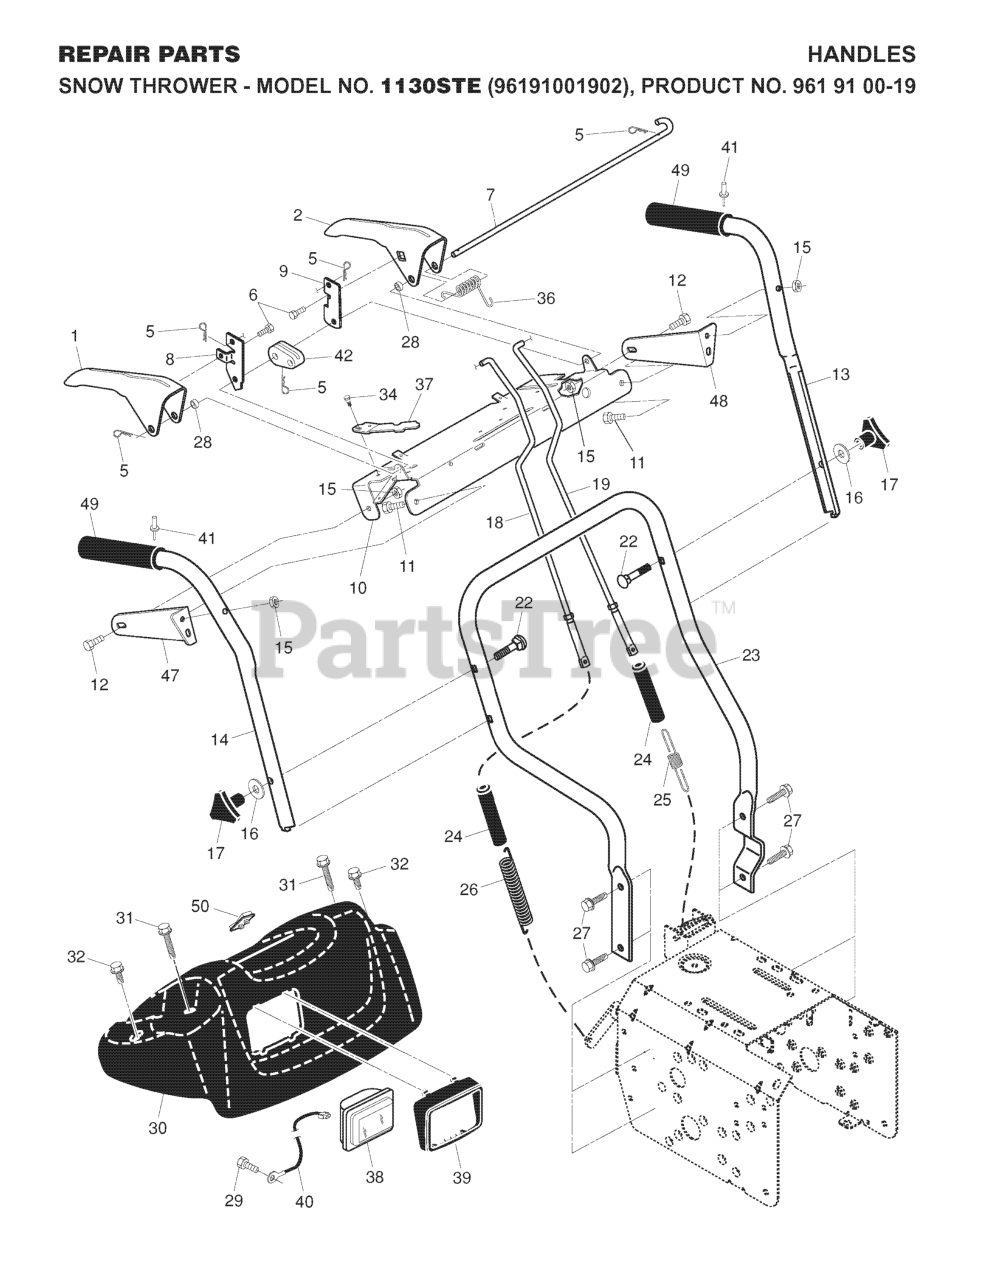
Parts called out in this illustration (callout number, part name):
1	LEVER.CONTROL.RH.PNT
2	LEVER.CONTROL.LH.PNT
5	SPRING RETAINER
7	BAIL.CONTROL.INTERLOCK
8	ARM,IMPELLER ROD
9	ARM.TRACTION.ROD.YZ
10	PANEL.CONTROL.PNT.BLACK
11	HEX BOLT
12	BOLT.FIN.HEX.5/16-18X3/4
13	TUBE.HANDLE.PLOW.LH.PNT
14	TUBE.HANDLE.PLOW.RH.PNT
15	NUT.LOCK.5/16-18
16	WASHER
17	KNOB.HANDLE.3/8.TRI-POINT.BLAC
18	ROD.ASM.IMPELLER
19	ROD.ASM.TRACTION.
22	BOLT 3/8-16 X 2-1/4
23	TUBE.LOWER.HANDLE.24.BLACK
24	SLEEVE, SPRING
25	SPRING, TRACTION DRIVE
26	SPRING, AUGER CONTROL
27	SCREW 3/8-16X1
28	SPACER CONTROL LEVER
29	Screw, Grounding
30	CONSOLE, PANEL
31	SCREW, HEX HD TAPPING #10-24 1
32	SCREW, HEX HEAD, TAPPING
34	SCREW 14-20 X 5/8
36	RP SPRING, TORSION
37	SPRING.INTERLOCK
38	HEADLIGHT.HALOGEN.SNOW
39	BEZEL.HEADLIGHT.BLACK
40	HARNESS.WIRE.LIGHT/GRIP.SNOW
41	RIVET.POP.1/8X
42	CAM.INTERLOCK.RELEASE
47	BRKT.PANEL.RH.INT
48	BRKT.PANEL.LH.INT
49	GRIP.HANDLE.HEATED
50	SWITCH.GRIP.HEATED
